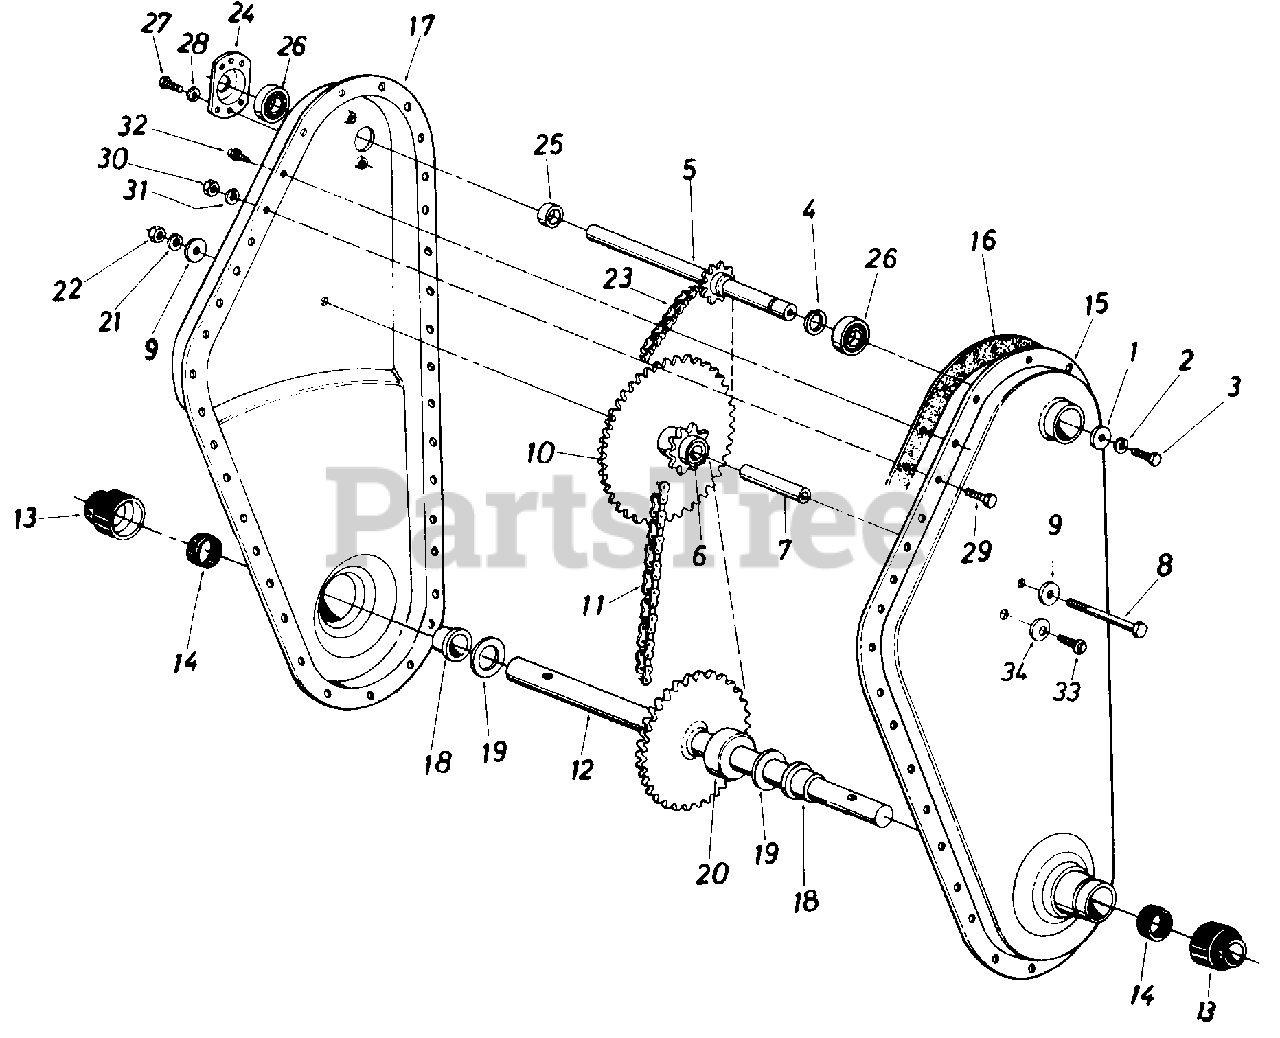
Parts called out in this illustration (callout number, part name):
1	Fl-Wash. 1/4" I.D. x .93" O.D. x . 1 20
2	L-Wash. 1/4" I.D."
3	Hex Bolt 1/4-28 x .62" Lg. w/Patch
4	External Snap Ring-5/8" Dia.
5	Input Shaft Ass'y.
6	Bearing 5/8" I.D. x 3/4" O.D. x 1.860" Lg.
7	Sprocket Hub Tubing 3/8" I.D. x 5/8" O.D. x 1.90
8	Hex Bolt 3/8-24 x 2.75" Lg.
9	Fl-Wash. 3/8" I.D. x 1.25" O.D. x .10
10	Sprocket Ass'y.
11	#50 Chain 5/8" Pitch x 46 0 Links Endless
12	Tine Shaft Ass'y.
13	Dust Cup
14	Seal Ring Single Lip, Springless
19	Fl-Thrust Wash. 1.0" I.D. x .03 0 Thk.
20	Step Spacer
21	L-Wash. 3/8" I.D.
22	Hex Nut 3/8-24 Thd.*
23	#35 Chain 3/8" Pitch x 52 Links Endless
24	Bearing Housing 1.38" I.D.
25	Spacer
26	Ball Bearing .625" I.D. x 1.38" O.D. x .437
27	Hex Wash. SF-Tap Scr. 1/4-20 x .50" Lg.
28	L-Wash. 1/4" I.D.
29	Hex Bolt 5/16-18 x .75" Lg.
30	Hex Nut 5/16-18 Thd.
31	L-Wash. 5/16" I.D.*
32	Hex Wash. SF-Tap Scr. 1/4-20 x.50" Lg.
33	Hex Wash. Hd. Tap Scr. 1/4-20 x.38" Lg.
34	Bell-Wash. .265" I.D. x .75" O.D.
